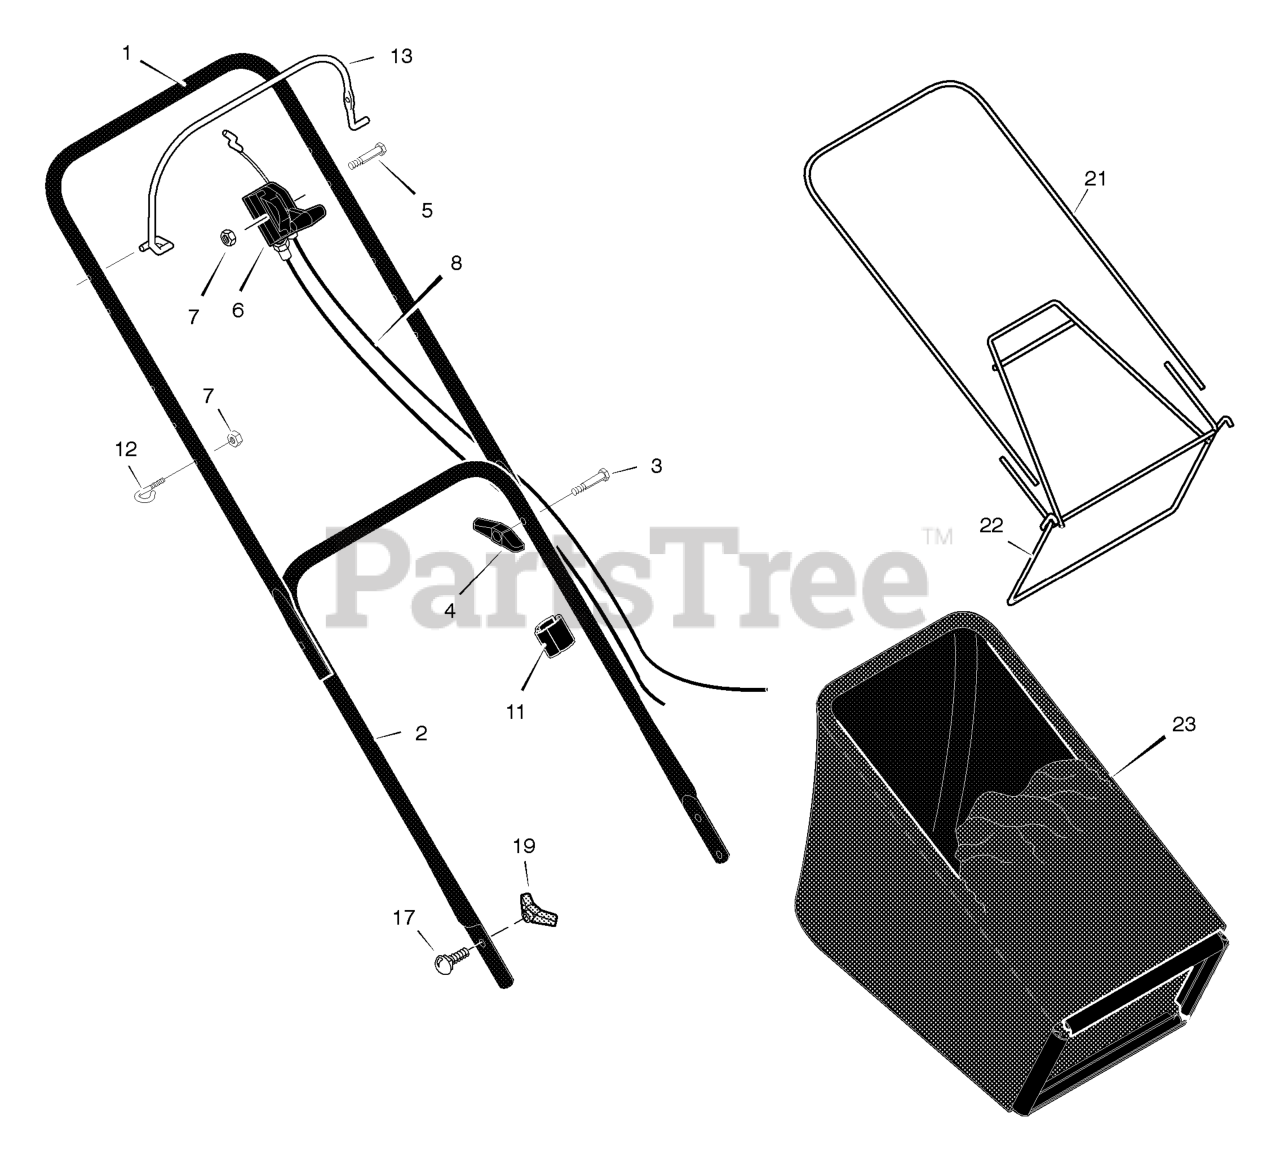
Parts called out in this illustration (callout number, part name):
1	Handle, Upper (Black)
2	Handle, Lower (Black)
4	Knob, Plastic
6	Throttle Control
7	Locknut
8	Engine Stop Cable
11	Clip, Cable
12	Guide, Rope
13	Lever, Engine Stop
17	Bolt, Carriage
19	Knob, Plastic
21	Frame, Top
22	Frame Assembly
23	Bag, Cloth
